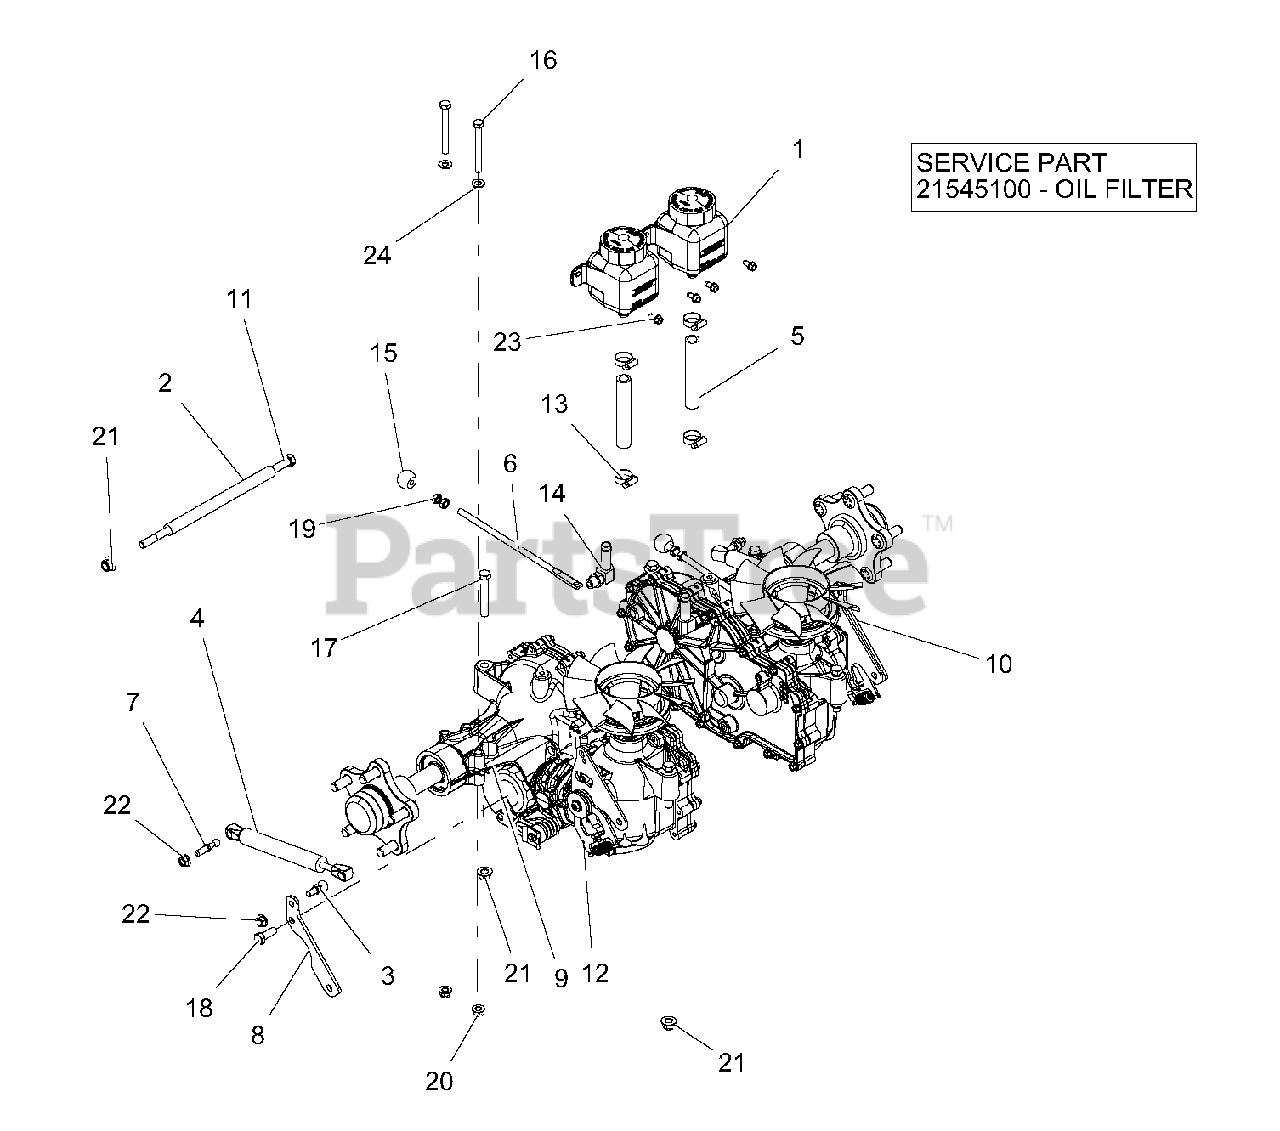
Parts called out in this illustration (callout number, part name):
1	TANK, EXPANSION ZT2800
2	SPACER, 3/8 ID X 5/8 OD X 7.72
3	STUD-BALL
4	DAMPER,
5	HOSE, PT100 HYDRO OVERFLOW
6	LEVER, PT100 DUMP VALVE
7	STUD, BALL THREADED
8	PLATE, TRANSMISSION DAMPER MTG
9	TRANSAXLE, 3200 SERIES - RH
10	TRANSAXLE, 3200 SERIES - LH
11	BLT, HEX .38-16X11.00 GR5 YWZC
12	PIN-HAIR INT .06X.18X.77
13	CLAMP, .88 DIA HOSE
14	FITTING, HYD (90 DEG)
15	KNOB, BALL -BLACK .312-18
16	@BLT-HEX .31-18X3.00 GR5 YWZC
17	@BLT-HEX .38-16X2.50 GR5 YWZC
18	@BLT-HEX .38-16X1.00 GR5 YWZC
19	NUT, JAM .312-18 YWZC
20	NUT-LK-NYL-FLG .31-18 YWZC
21	NUT-LK-NYL-FLG .38-16 YWZC
22	@NUT, LK-TOP-FLG .312-18 YWZC
23	SCR-TAP .25-20X.50 HWH TR YWZ
24	@WSHR-FL-STL.344X.688X.065YWZC
